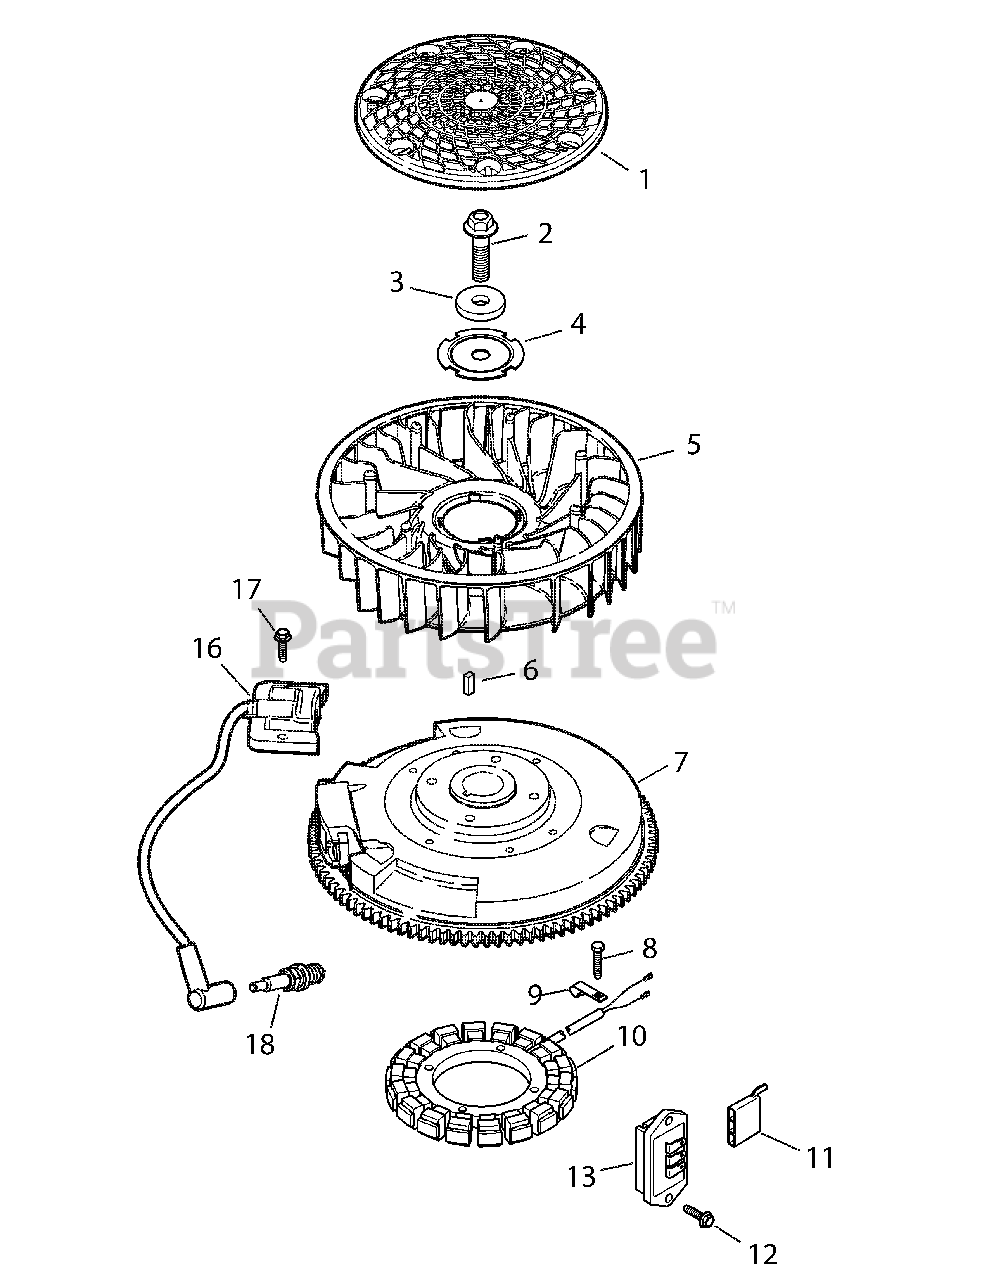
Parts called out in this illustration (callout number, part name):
2	Hex Flange Screw
4	Fan Mounting Plate
6	Straight Flywheel Key
7	Flywheel
8	Thd. Frm. Screw, M5 X 0.8 X 25
10	15 Amp Stator Kit (Inc. KH-25-452-01-S)
12	Flg. Thd. Frm. Screw, M5 X .8 X 20
13	Regulator/Rectifier
16	Ignition Module (CDI Fixed)
17	Flg. Thd. Frm., M5 X .8 X 20
18	Spark Plug (Std)
